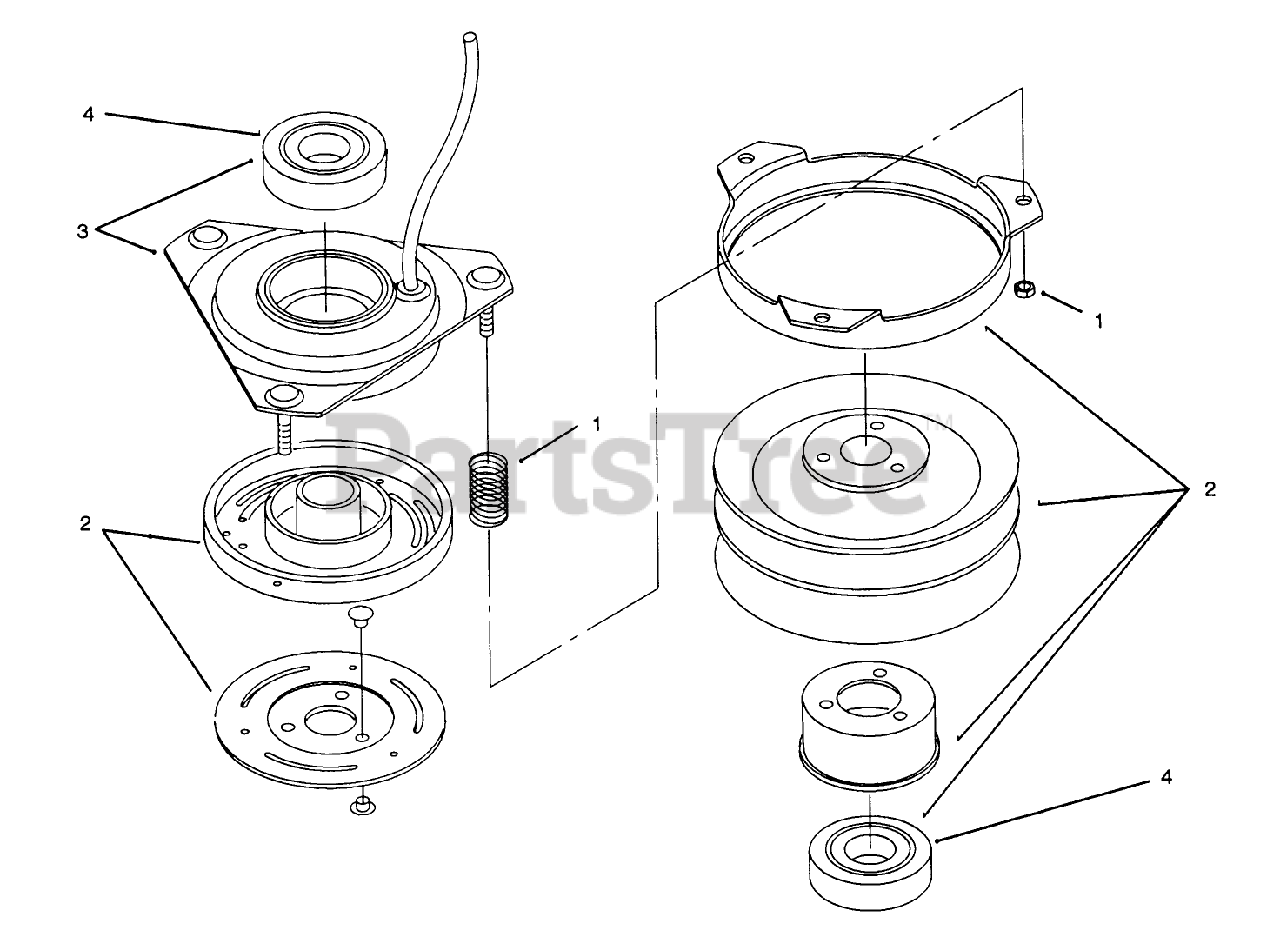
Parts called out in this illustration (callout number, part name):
1	ACCESSORY PKG SRVC PART
2	ROTOR & ARMATURE ASSY
3	FIELD ASSY (SRVC PART)
4	BEARING-ELEC CLUTCH
